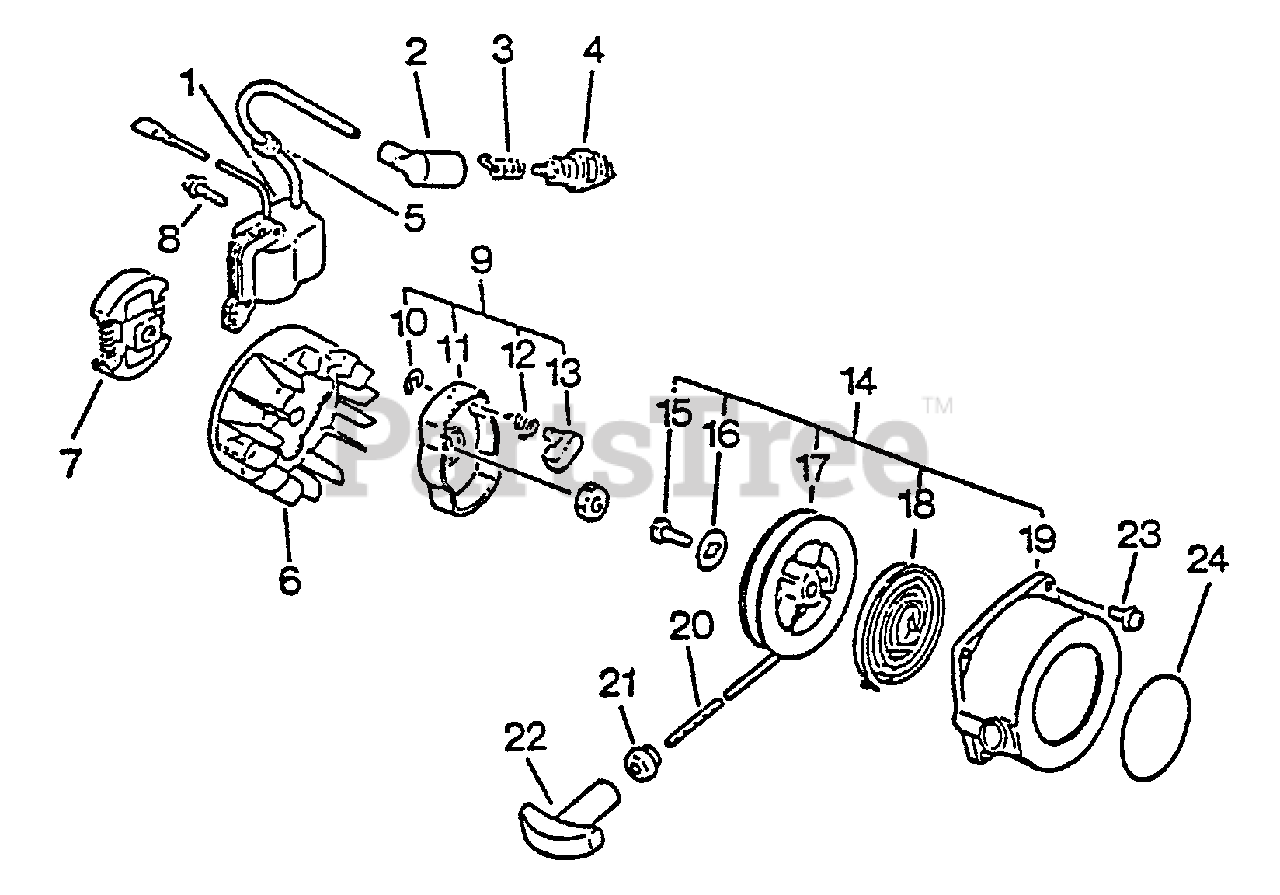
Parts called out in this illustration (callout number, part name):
1	COIL, IGNITION
2	CAP, SPARK PLUG
3	TERMINAL, SPARK PLUG CAP
4	SPARK PLUG -- BPM-7A
4	SPARK PLUG -- CJ-7Y
4	SPARK PLUG -- BPMR-7A
4	SPARK PLUG -- RCJ-7Y
5	GROMMET
6	FLYWHEEL
7	CLUTCH ASSY
8	SCREW - 4X22
9	STARTER PAWL ASSY
10	RING, RETAINING - 4
11	CATCHER, PAWL
12	SPRING, RETURN
13	PAWL, STARTER
14	STARTER ASSY
16	WASHER
17	REEL, ROPE
18	SPRING, REWIND
19	CASE, STARTER
20	ROPE, STARTER - 3X890
21	GUIDE, ROPE
22	GRIP, STARTER
23	SCREW - 4X16
24	LABEL - ECHO
